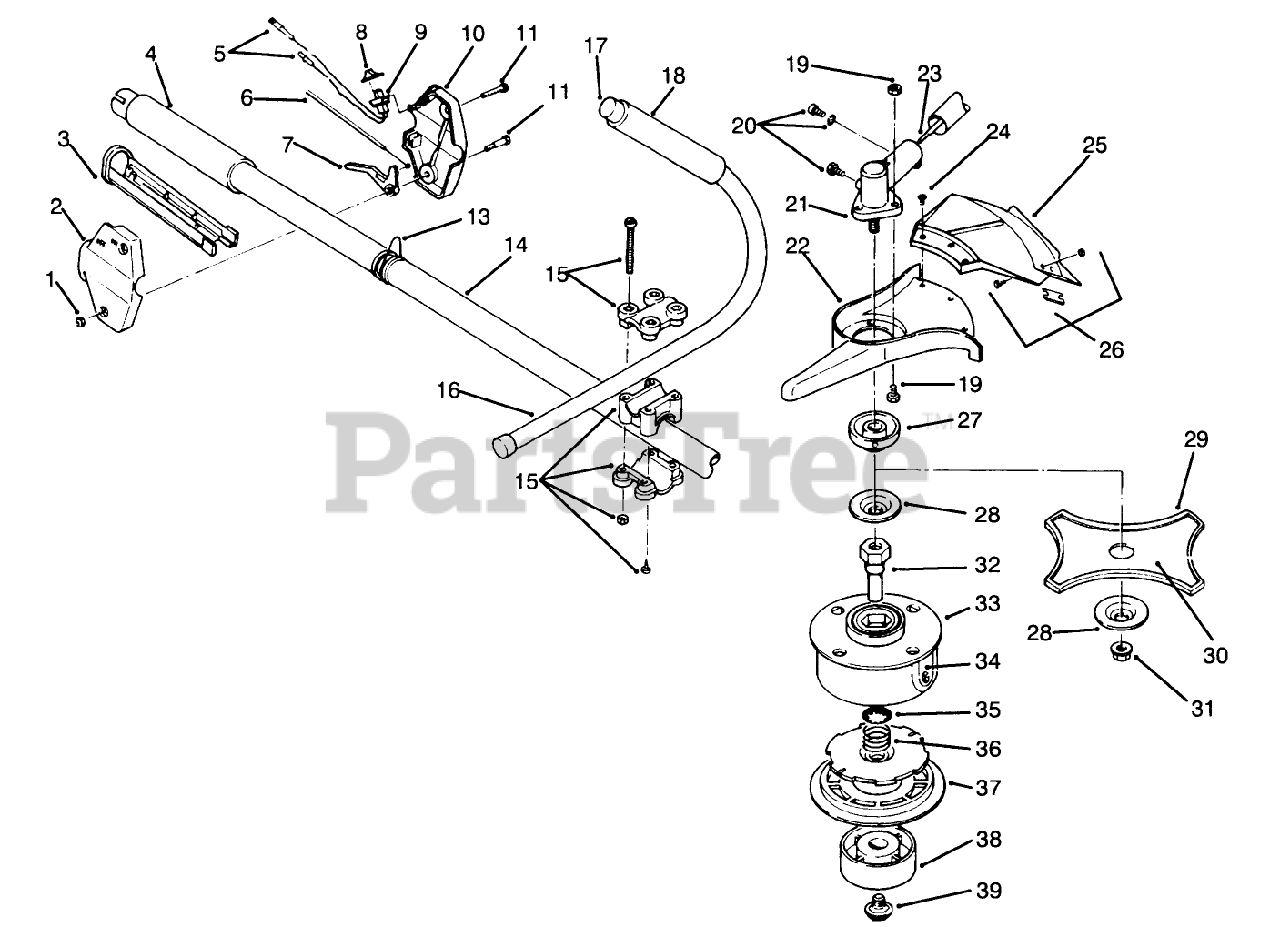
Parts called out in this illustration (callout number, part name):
1	NUT-LOCK, NI
3	TROUGH 1"
4	GRIP - RUBBER
5	LEAD WIRE ASM
8	SWITCH COVER
9	SWITCH
10	HOUSING LH
14	DRIVE SHAFT HSG ASM
15	HANDLE BRACKET ASM
17	TUBE CLOSURE
18	HANDLE NITRILE GRIP
20	MTG HDW&PLUG SET
23	FLEXIBLE DRIVE SHAFT
24	GUARD MNTG SCREW ASM
25	GUARD & BLADE ASM
26	BLADE ASM
29	BLADE SAFETY GUARD
31	BLADE RETAINER NUT
34	EYELET
35	RETAINER
36	SPRING
